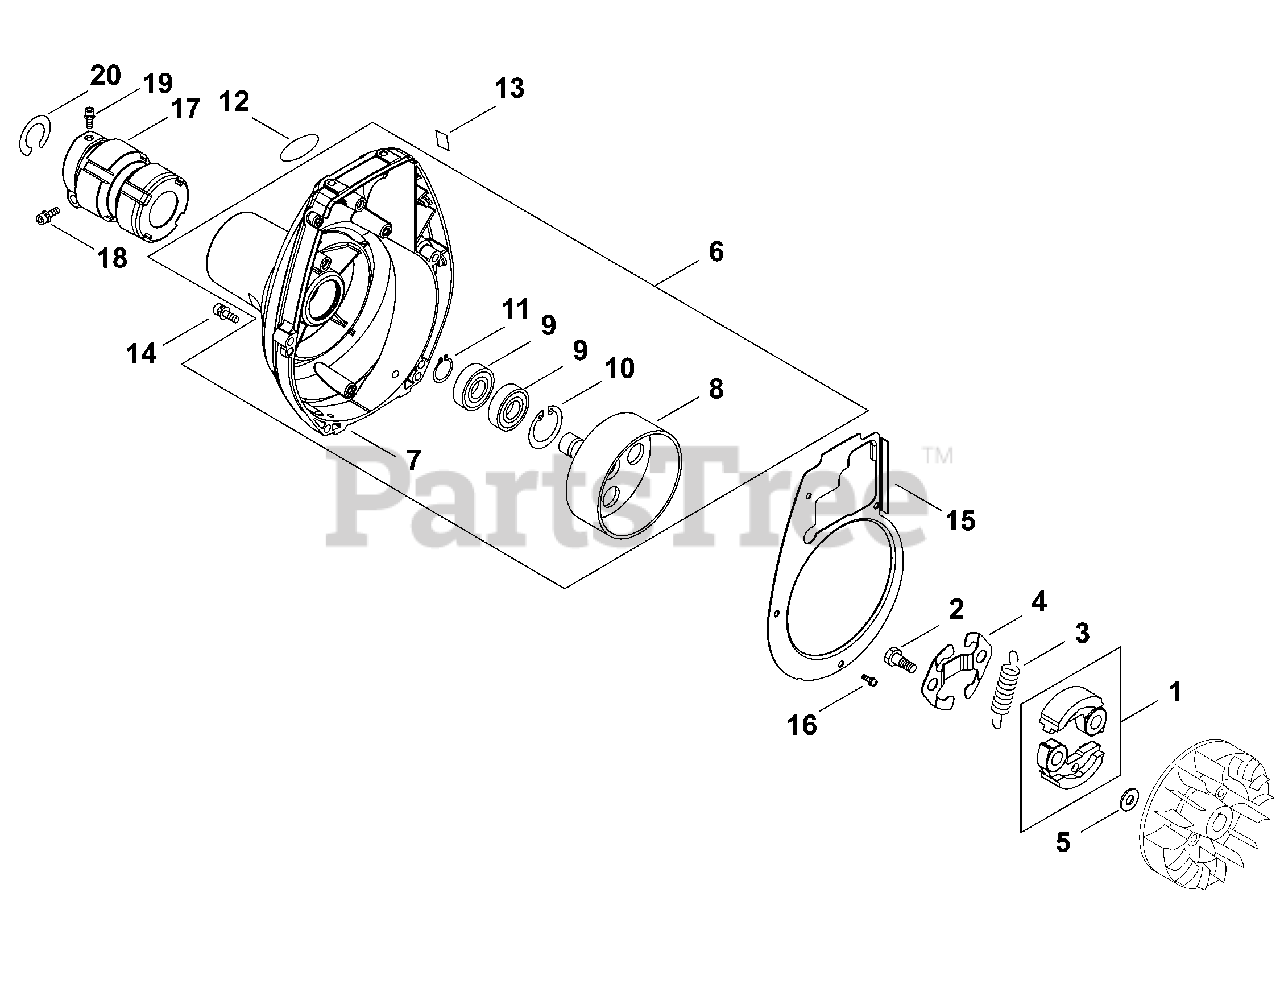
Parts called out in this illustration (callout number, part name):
1	SHOE, CLUTCH
2	BOLT, CLUTCH
3	SPRING, CLUTCH
4	SPRING, FLAT
5	WASHER 8.2×17×1.6
6	COVER ASSY, FAN
7	COVER, FAN
8	DRUM, CLUTCH
9	BEARING, BALL 6001
10	RING, SNAP 28
11	RING, RETAINING - 12
12	LABEL - MODEL B460
13	LABEL, CAUTION - HOT
14	BOLT 5×25
15	SHIELD, FAN
16	SCREW 4×10
17	CUSHION
18	BOLT 5×28
19	BOLT 5×12
20	RING, RETAINING Ø45
